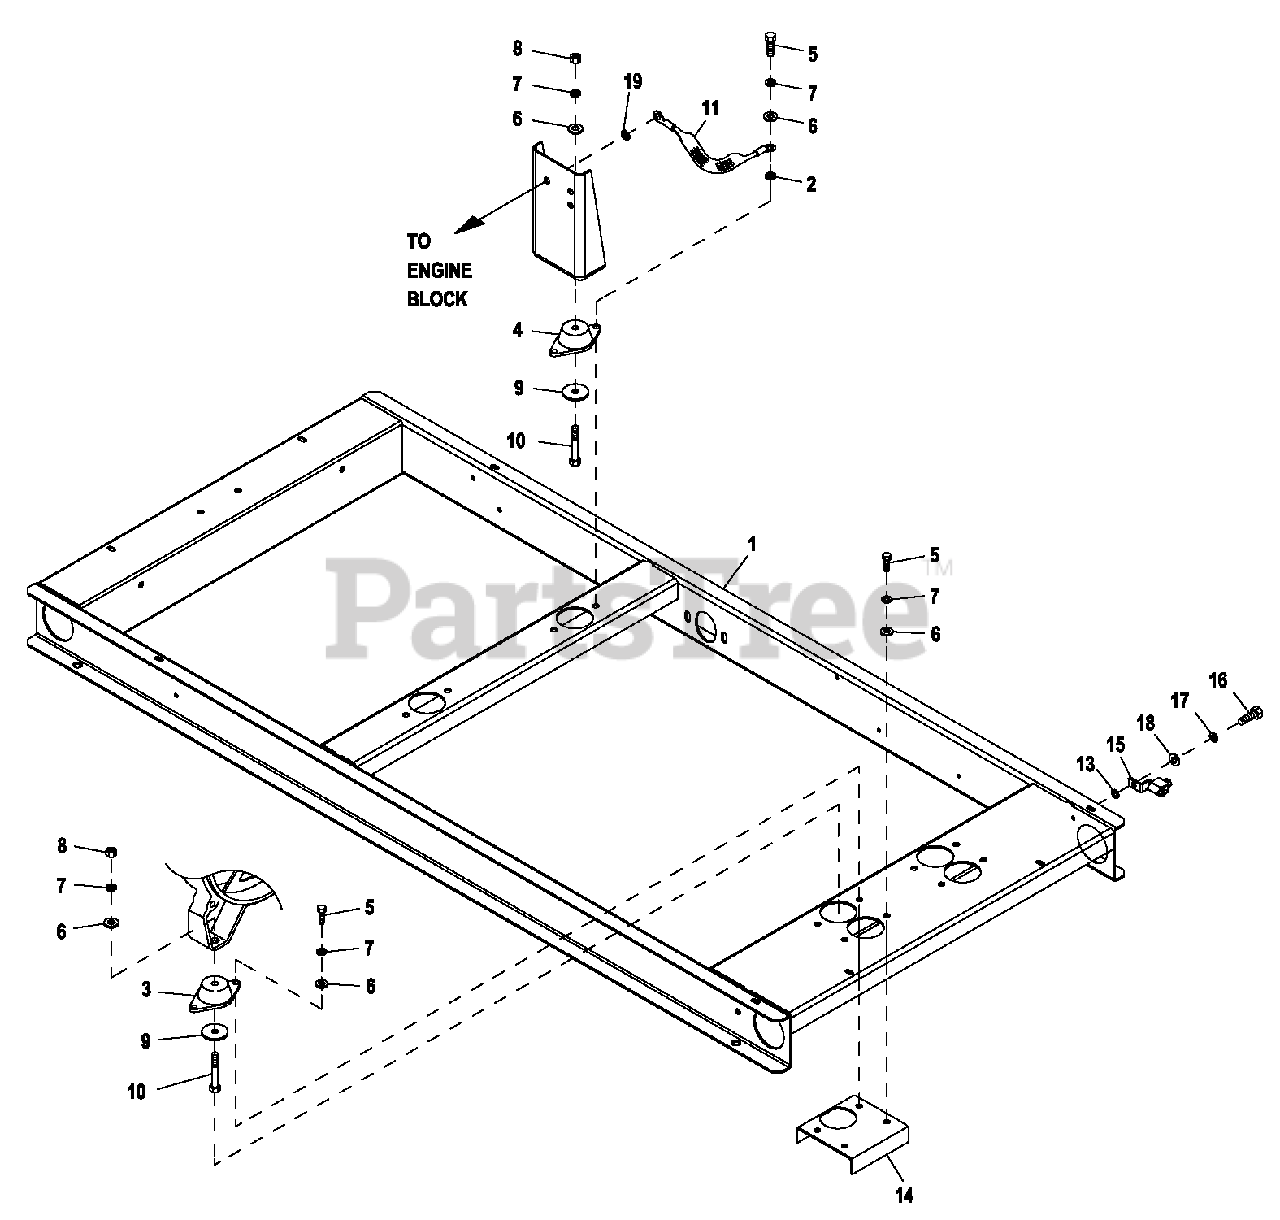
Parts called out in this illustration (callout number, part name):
1	MOUNTING BASE 1,6L 2007 C1
2	WASHER SHAKEPROOF EXT 5/16 STL
3	DAMPENER VIBRATION
4	VIB. ISO. 70-75 DURO
5	SCREW HHC M8-1.25 X 20 G8.8
6	WASHER FLAT 5/16 ZINC
7	WASHER LOCK M8-5/16
8	NUT HEX M8-1.25 G8 YEL CHR
9	WASHER FLAT M8
10	SCREW HHC M8-1.25 X 60 G8.8
11	EARTH STRAP
13	WASHER SHAKEPROOF EXT 1/4 STL
14	ALTERNATOR SUPPORT BLOCK OFF
15	LUG SLDLSS #2-#8 X 17/64 CU
16	SCREW HHC M6-1.0 X 20 C8.8
17	WASHER LOCK M6-1/4
18	WASHER FLAT 1/4-M6 ZINC
19	WASHER LOCK EXT 7/16 STL
